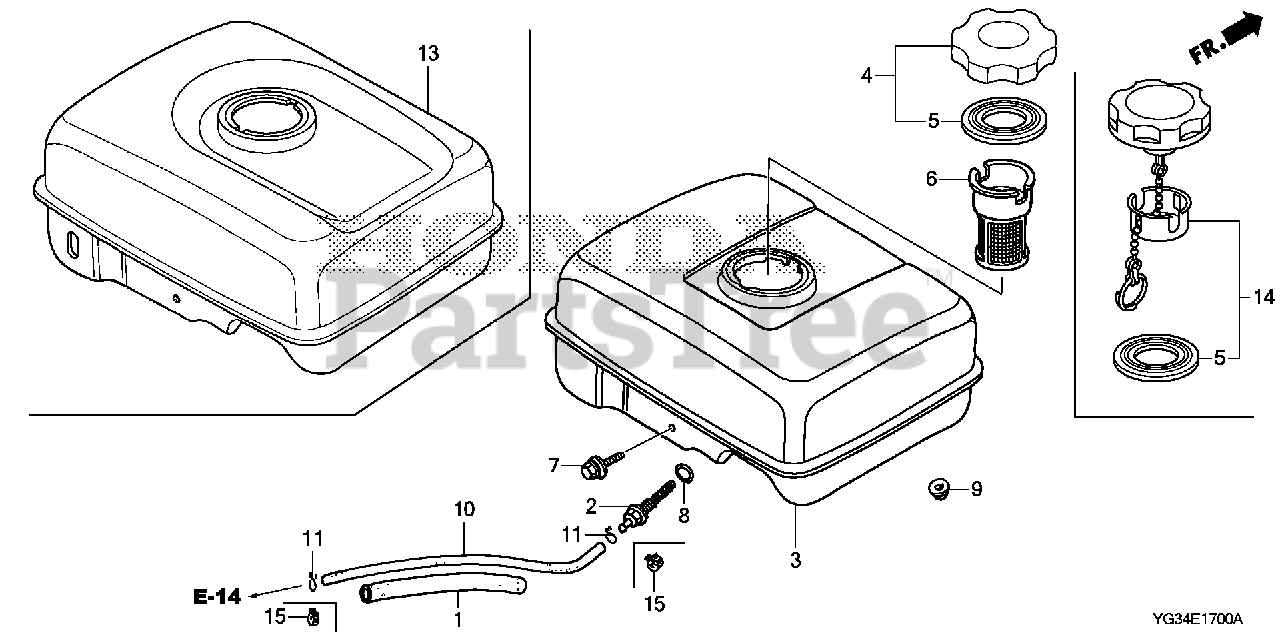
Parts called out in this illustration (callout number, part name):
1	RUBBER, SUPPORTER (107MM)
2	JOINT, FUEL TANK
3	TANK, FUEL *NH31* (MCKINLEY WHITE)
5	GASKET, FUEL FILLER CAP (39X62X3) (RADICON)
6	FILTER, FUEL
7	BOLT, FLANGE (6X29)
8	O-RING (13.5X1.5) (ARAI)
8	O-RING (14MM) (NOK)
9	NUT, FLANGE (6MM)
10	TUBE, FUEL (4.5X140) (FKM)
13	TANK, FUEL *NH31* (GAUGELESS) (MCKINLEY WHITE)
14	CAP, FUEL FILLER
15	CLAMP, TUBE (D8)
